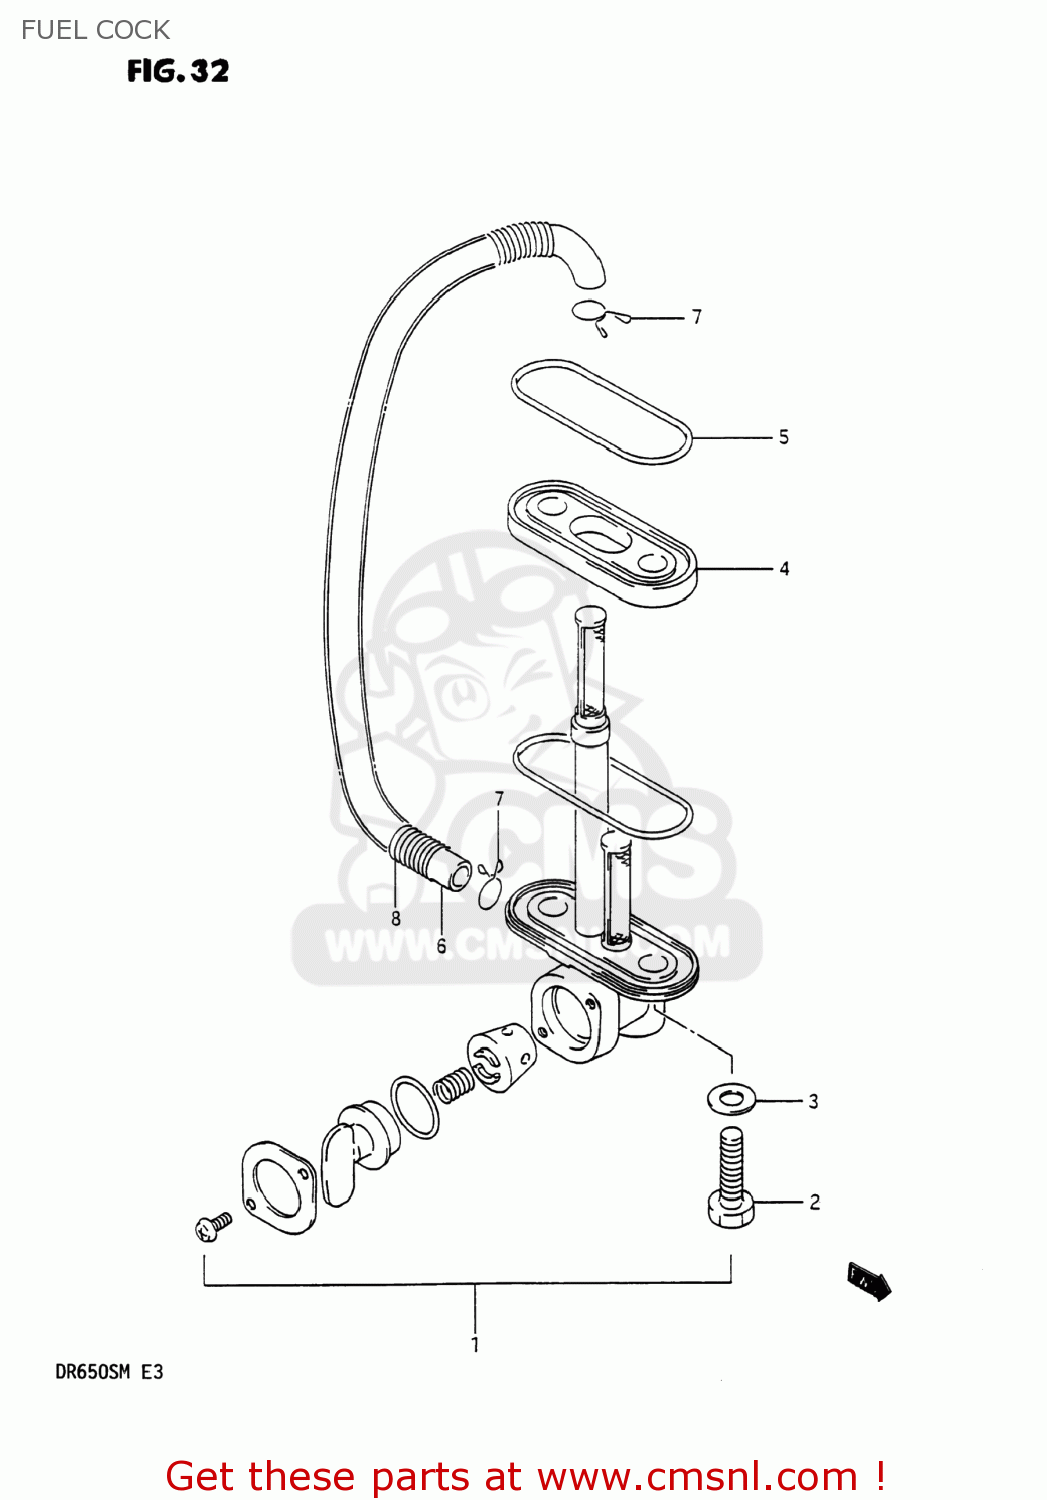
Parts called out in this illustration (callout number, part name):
1	COCK ASSY,FUEL
2	BOLT(6X20)
3	GASKET(6.4X11.5X0.8) (NAS)
4	SPACER,FUEL COCK
5	GASKET,FUEL COCK (NAS)
6	HOSE
7	CLIP
8	SPRING
